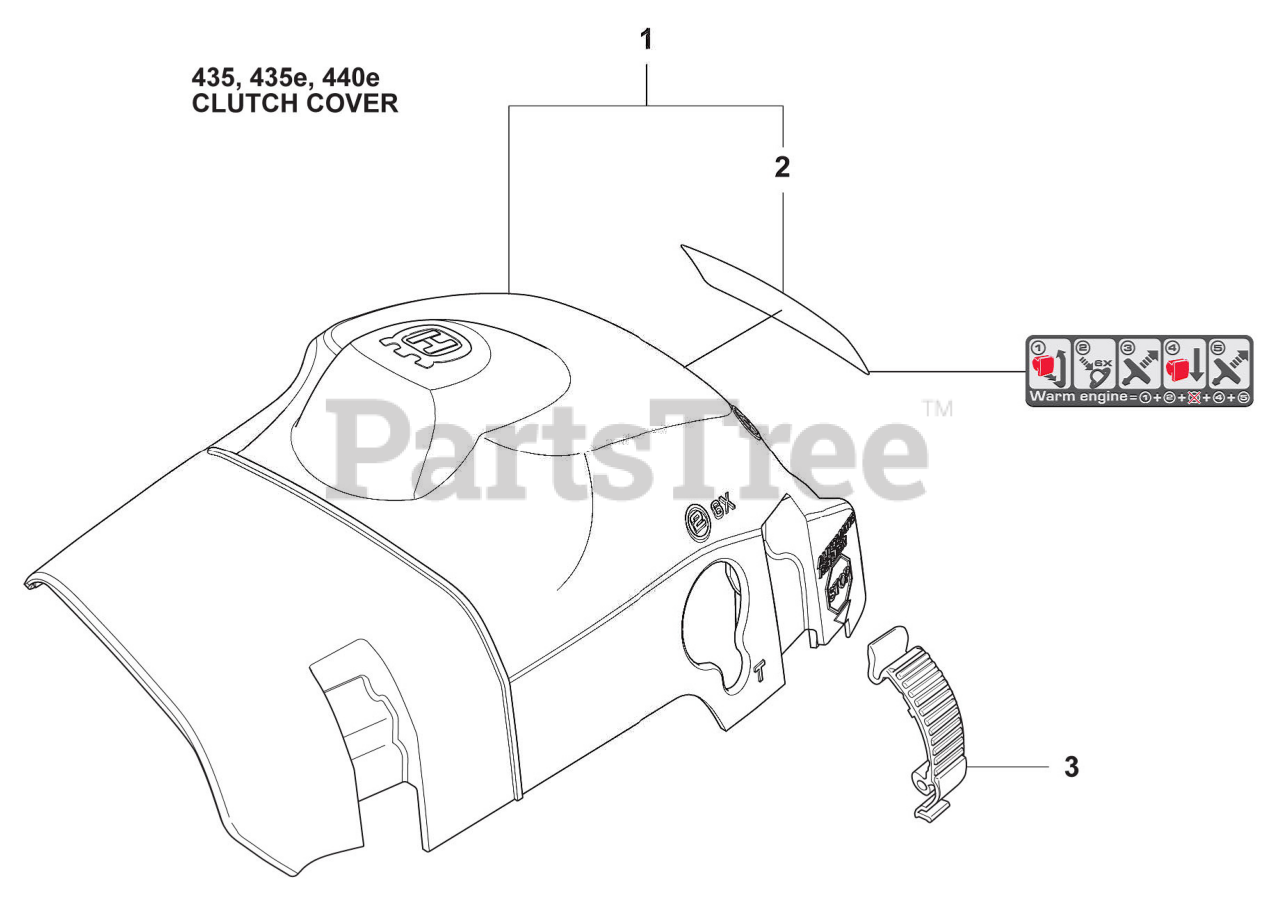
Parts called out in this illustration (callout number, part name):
1	Cylinder Cover Assembly
2	Start Reminder Label
3	Top Cover Buckle Clip, Orange
